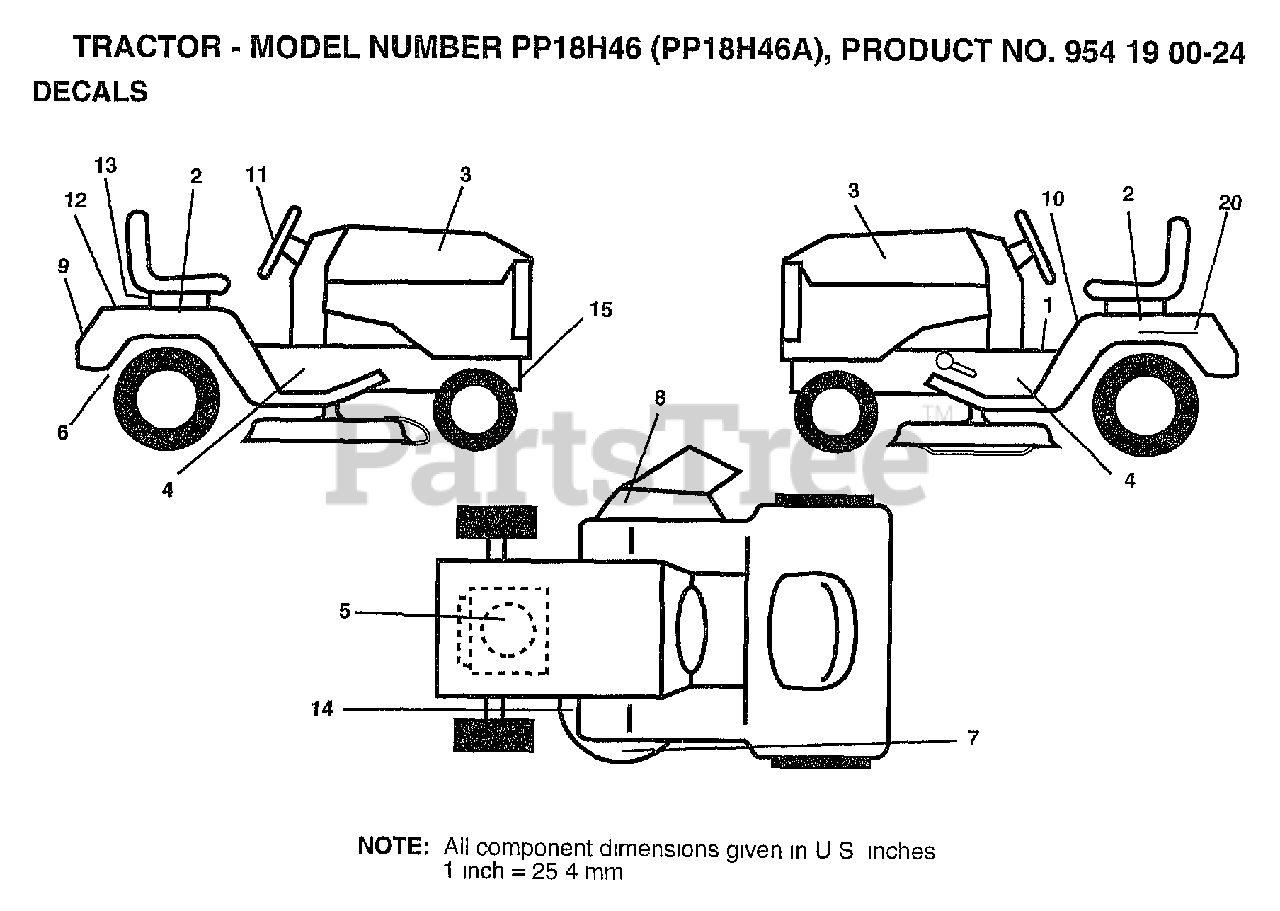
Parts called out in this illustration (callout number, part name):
1	"DECAL FENDER,OPER"
2	DECAL FENDER AUTO
3	DECAL HOOD PREDAT
4	DECAL CHAISSIS
5	DECAL HP ENGINE
6	DECAL DRAWBAR LH
7	"DECAL,ENVIRO DECK"
8	"DECAL, WARNING"
9	DECAL FENDER DOME
10	DECAL.CAUT.ENG/FR
11	DECAL INS STRG WH
12	DECAL FENDER PRED
13	RETAINER-SPRING
15	DECAL CHASSIS PRE
20	DECAL.BATRY.3-3908
